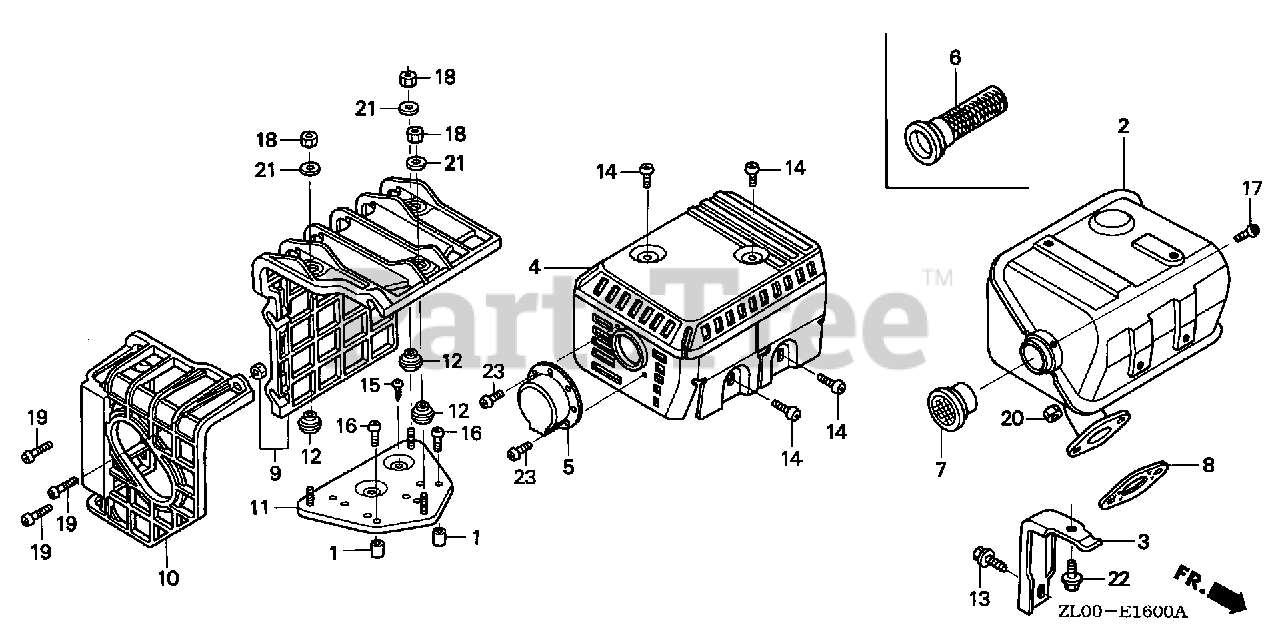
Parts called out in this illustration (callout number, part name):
2	MUFFLER (ARRESTER)
3	STAY, MUFFLER
4	PROTECTOR, MUFFLER (SILENT)
5	CAP, MUFFLER
6	ARRESTER, SPARK
8	GASKET, MUFFLER
13	BOLT, FLANGE (6X13) (CT200)
14	SCREW, TAPPING (5X8)
17	SCREW, TAPPING (4X6)
20	NUT, HEX. (8MM)
22	BOLT, FLANGE (6X12)
23	SCREW, TAPPING (4X6)
